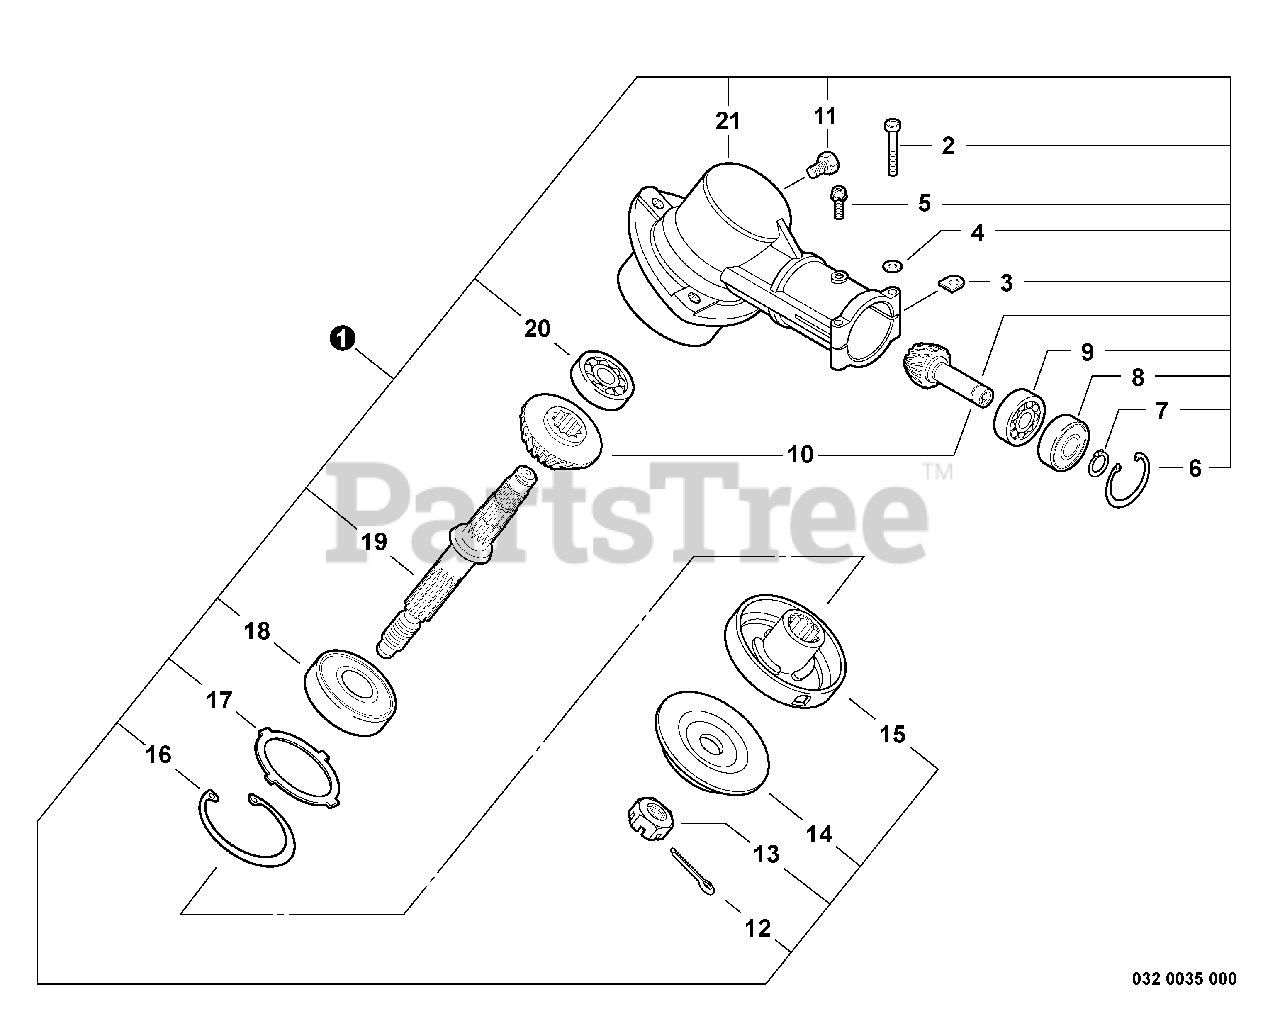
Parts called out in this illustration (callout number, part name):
1	GEAR CASE ASSY
2	BOLT - 5X35
3	WASHER - 5
5	SCREW - 5X10
6	RING, RETAINING - 22
7	RING, RETAINING - 10
8	BEARING, BALL - 6900Z
9	BEARING, BALL - 6900
10	GEAR SET - BEVEL
11	BOLT - 8X8
12	PIN, SPLIT - 2X22
13	NUT - 10 -- LEFT HAND
14	ADAPTOR, BLADE - LOWER
15	ADAPTOR, BLADE - UPPER
16	RING, RETAINING - 32
18	BEARING, BALL - 6201
19	GEAR - SHAFT
20	BEARING, BALL - 609
21	CASE, GEAR
